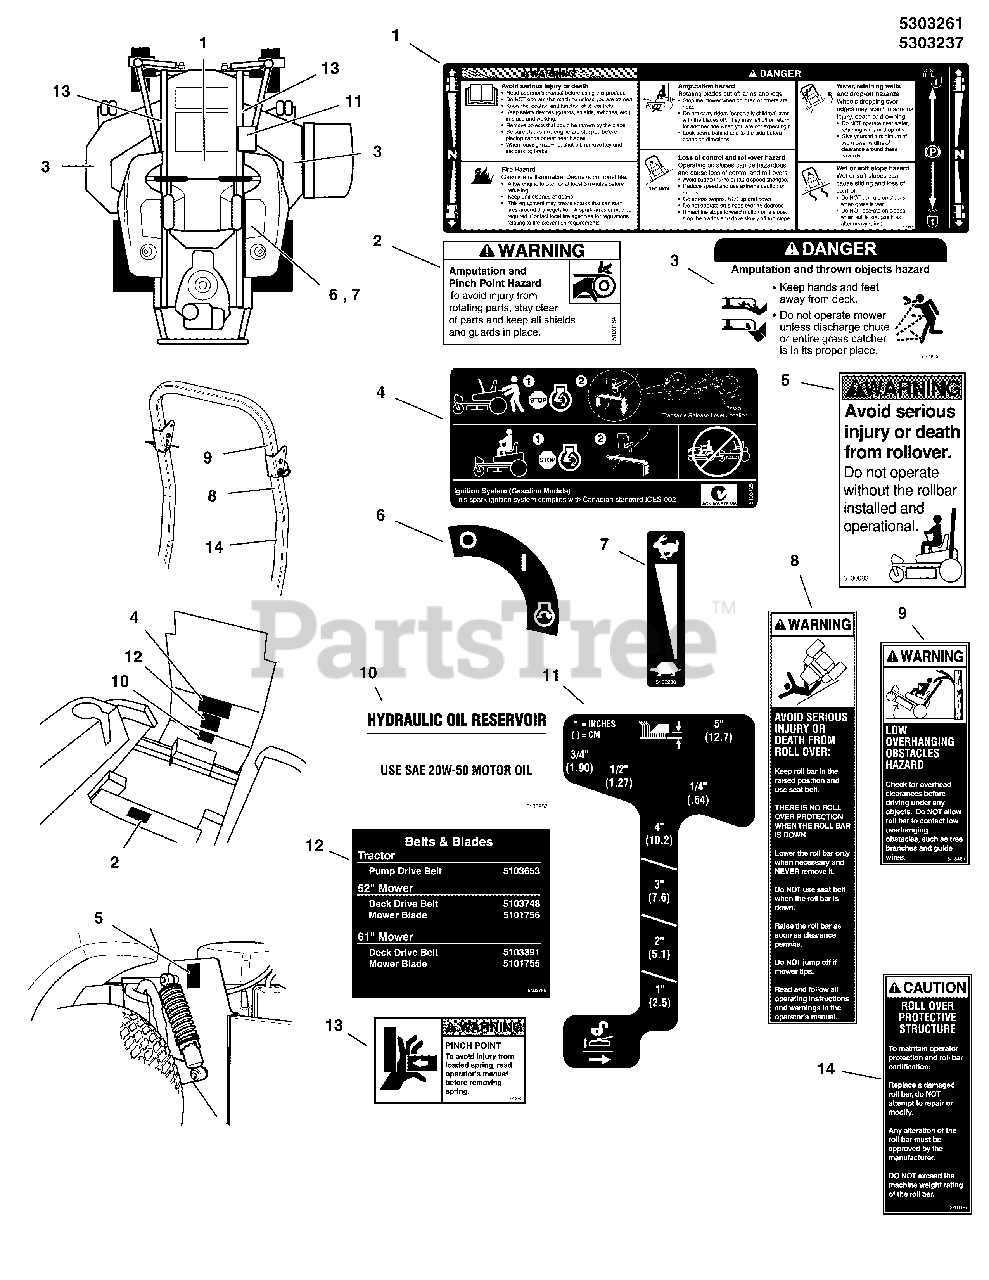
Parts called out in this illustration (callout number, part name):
1	DECAL, MAIN SAFETY
2	DECAL, WARNING, HAND IN BELT, ENG ONLY
3	DECAL, DANGER DO NOT OPERATE W/O DEFLECT
4	DECAL, TRANSAXLE RELEASE, 600/700
5	DECAL, WARNING, ROLL BAR
6	DECAL, IGNITION SWITCH
7	DECAL, THROTTLE CONTROL
8	DECAL, WARNING, FOLDING ROPS
9	DECAL, WARNING OVERHANG, ROPS
10	DECAL, HYDRAULIC OIL, SAE 20W50
11	DECAL, CUT HEIGHT, IS700/ZTS700
12	DECAL, BELT & BLADE, IS700Z/ZTS700
13	DECAL, PINCH POINT
14	DECAL, CAUTION, FOLDING ROPS
